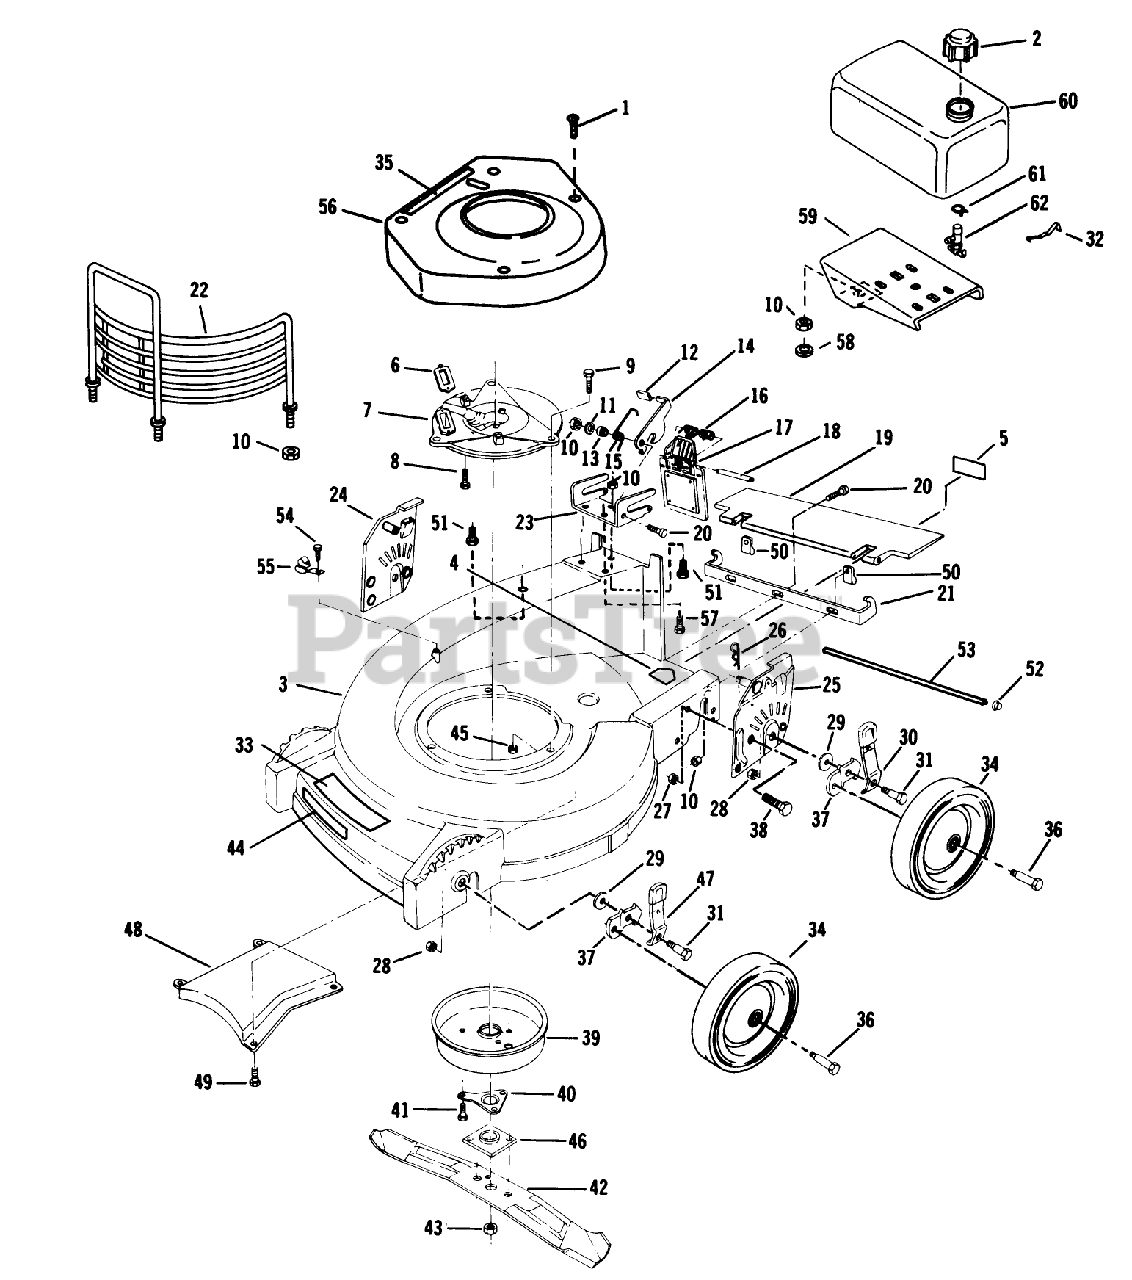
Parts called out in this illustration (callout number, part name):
1	SCREW - SELF TAPPING
2	FUEL CAP & INSERT
8	SCREW V
9	SCREW-HH
10	LOCKNUT E
15	SPRING
16	SPRING ASOC
18	ROD (RB&W)
19	T/SHIELD SM&P
25	HANDLE BRACKET LH
26	HAIR PIN
27	NUT-LOCK F
28	LOCKNUT
29	WASHER
31	BOLT
32	SPRING
34	WHL & TIRE AY
36	BOLT-SHOULDER
39	MUFFLER COVER F
40	SUPPORT F
41	SCREW
43	NUT-BLADE
45	NUT-LOCK F
46	PLATE AND COLLAR ASM
48	BAFFLE CHUTE PL
51	SCREW HEX WASHER
54	SCREW LAWRENCE
56	SHROUD S
57	SCREW
58	WASHER
61	CLAMP - HOSE S
62	VALVE&SCREEN SM
